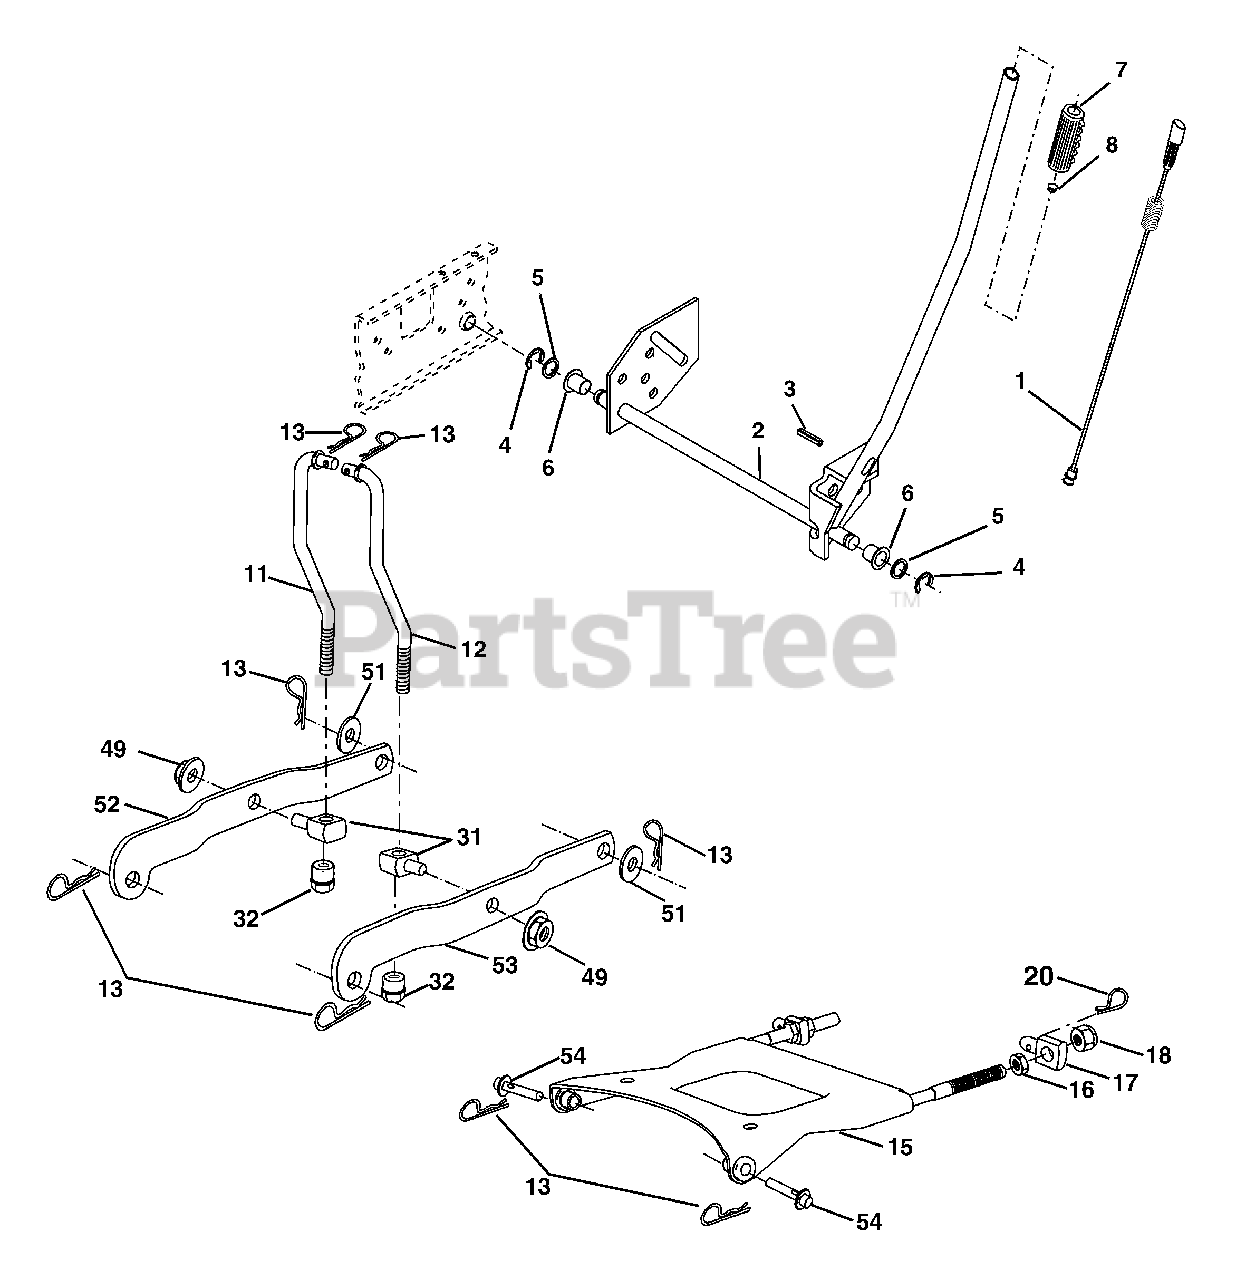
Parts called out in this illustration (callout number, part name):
1	Wire Asm Inner/Sprg W/plunger
2	Shaft Asm Lift RH w/Inf
3	Pin Groove
4	E Ring #5133-62
5	Washer 21/32 X 1 X 21 Ga
6	Bearing Nylon Blk 629 Id
7	Grip Handle
8	Button Plunger
11	Link Lift LH
12	Link Lift RH
13	Retainer Spring
15	Plate Asm Suspension
20	Retainer Spring
31	Trunnion
32	Nut Lift Link
39	Upstop
42	Nut 3/8-16
43	Washer 13/32 x 1 x 12 Ga.
44	Bolt 3/8-16 x 1
49	Nut Hex Flange Lock
51	Washer 17/32 x 7/8 x 13 Ga.
52	Arm Suspension Rear LH
53	Arm Suspension Rear RH
54	Pin Flange
